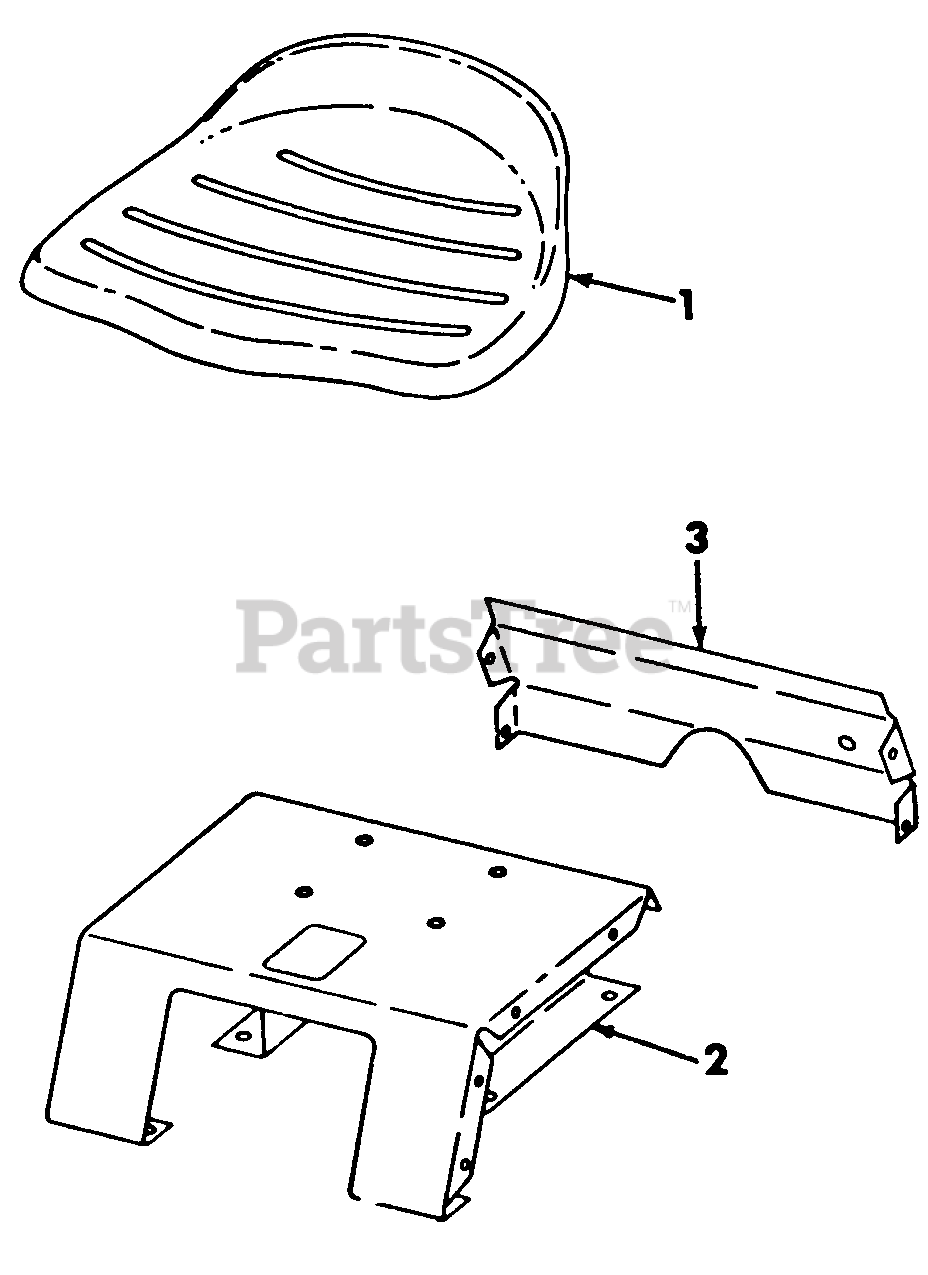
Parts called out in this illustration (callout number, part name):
1	Seat Assy
2	Cover & Seat Support Assy, Rear Frame
3	Panel Assy, Rear Frame Cover Back
